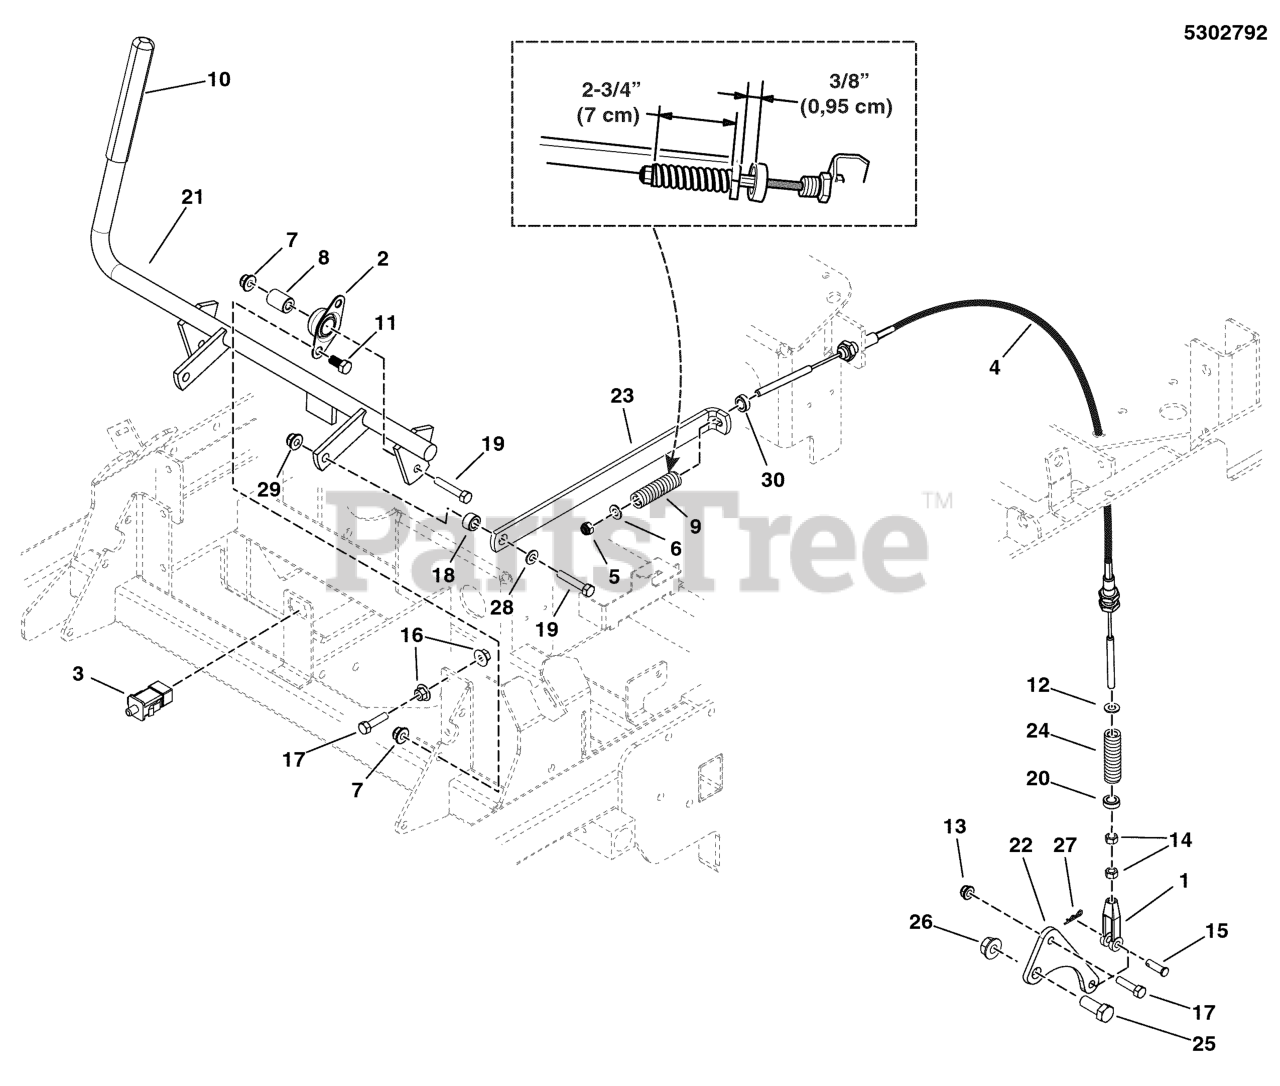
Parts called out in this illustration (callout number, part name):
1	CLEVIS, 5/16-24, STEEL, CLEAR ZINC
2	BEARING, BRONZE FLANGE, 3/4
3	SWITCH, DP NO/NC SNAP-IN
4	CABLE, PARKING BRAKE, S200XT
5	NUT, 5/16-24 HEX NYLON LOCK
6	WASHER, 5/16" SAE
7	NUT, 5/16-18 HEX NYLON LOCK
8	SPACER, .32 X .75 X 1.06
9	SPRING, COMP. 1/2 ID X .140 WIRE X 3.25
10	GRIP, FOAM, 3/4 ID X 6 X .187
11	BOLT, 5/16-18 X 3/4 GD5
12	WASHER, 1/2 USS
13	NUT, 5/16-18 HEX NYLON LOCK
14	NUT, 5/16-24 HEX
15	PIN-CLEVIS, 5/16 X 1 YZ
16	NUT, 5/16-18 HEX SERRATED FLANGE (LARGE)
17	BOLT, 5/16-18 X 1-1/4 GD5 YZ
18	SPACER, .38 X .50 X .31, CZ
19	BOLT, 5/16-18 X 1-3/4 GD5 YZ
20	BUSHING, DECK PIVOT
21	WELD, BRAKE SHAFT - BLK
22	PLATE, BRAKE ARM EXTENSION - BLK
23	LINK, BRAKE LOCK - BLK
24	SPRING, COMP, 1.1 X OD. X .085 WIRE X 5
25	BOLT, 1/2-13 X 1-1/4 GD5 CZ
26	NUT, 1/2-13 HEX SIDE LOCK
27	PIN, COTTER, 1/8 X 3/4
28	WASHER, 3/8 SAE
29	NUT, 3/8-16 HEX SIDE LOCK
30	COLLAR, 5/16 SET
